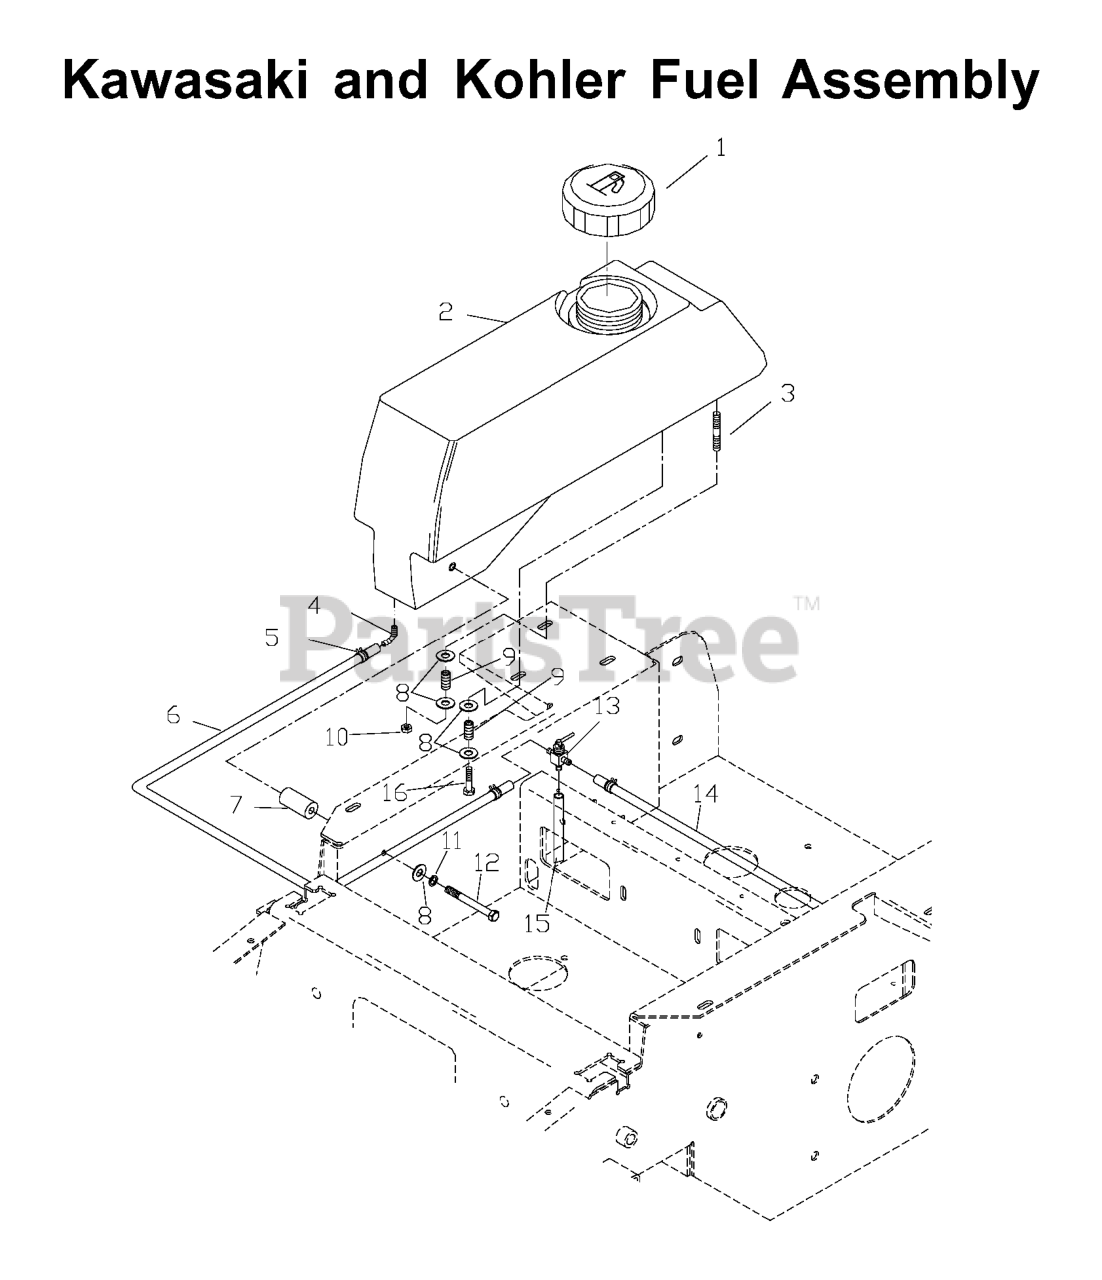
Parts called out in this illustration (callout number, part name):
1	FUEL CAP ANTI-SPLASH
2	FUEL TANK RT
3	STUD, 5/16C
4	HOSE BARB 90 DEGREE
5	HOSE CLAMP
7	TANK SPACER
8	WASHER 5/16 FLAT
10	NUT 5/16 NYLOC
11	WASHER.LOCK.HVY.HLCL.SPR.5/16
12	HCS 5/16C X 4
13	FUEL VALVE
15	FUEL LINE 29.5"
16	HCS 5/16C X 1
539104409	LEFT TANK W/CUP HOLDER
539104980	FUEL LINE 16"
